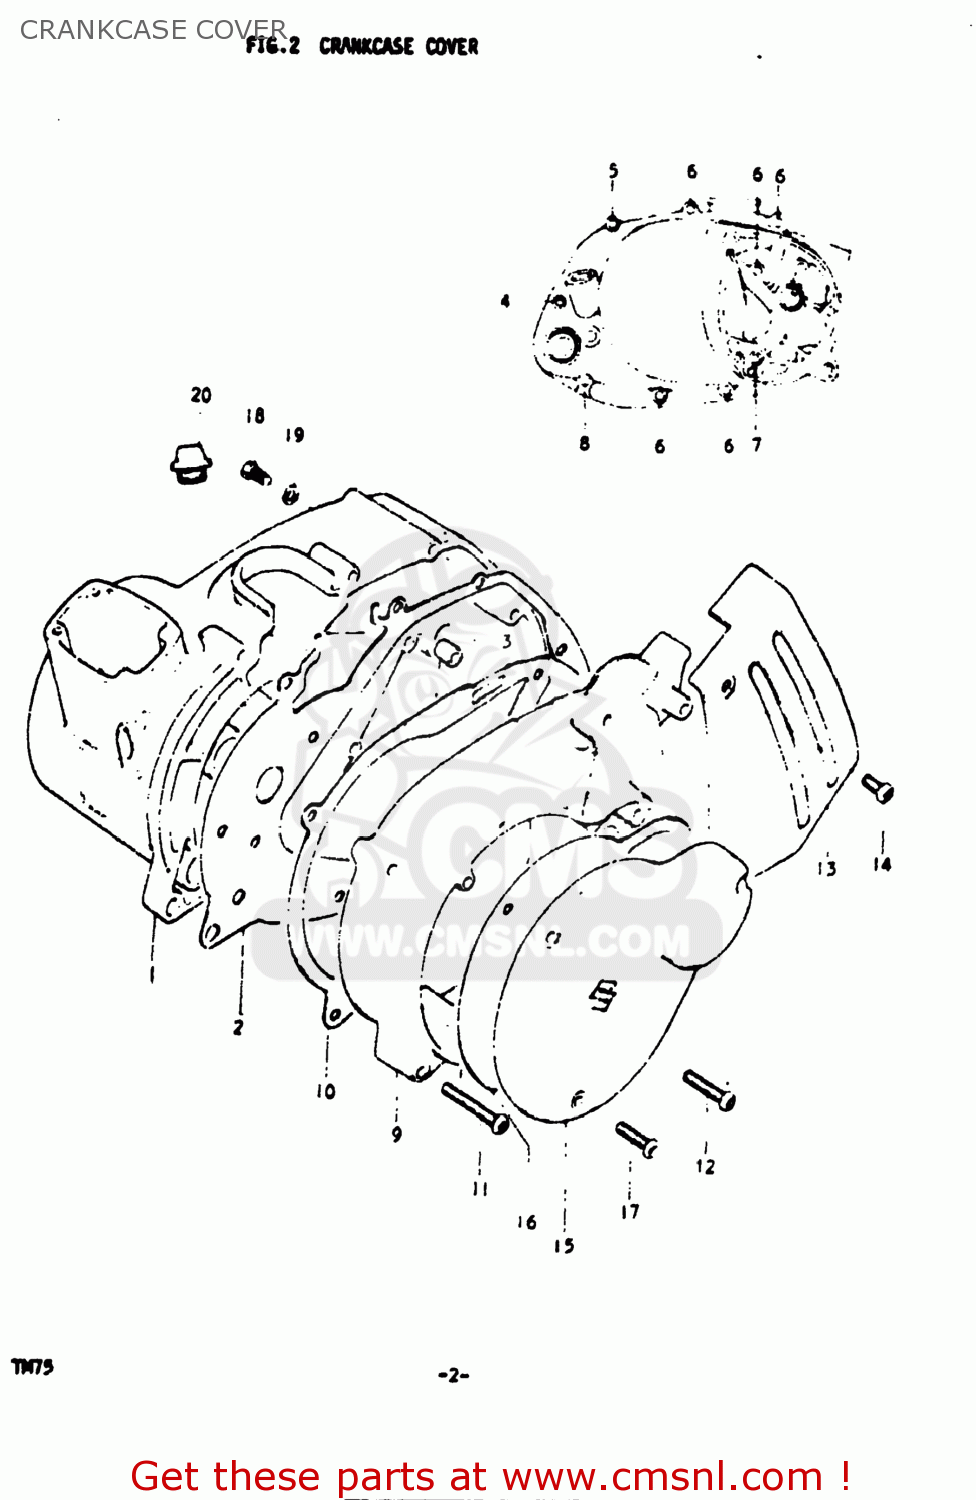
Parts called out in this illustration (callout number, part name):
1	COVER,CLUTCH
2	GASKET,CLUTCH COVER (MCA)
3	PIN
4	SCREW
5	SCREW
6	SCREW (6X35)
7	SCHROEF 5X80
8	SCREW
9	COVER
10	GASKET,MAGNETO COVER (NAS)
11	SCREW (6X35)
12	SCREW
13	COVER,SPROCKET
14	SCREW
15	COVER,SIGNAL GENERATOR
16	GASKET (MCA)
17	SCREW
18	SCREW(6X10)
19	GASKET(6.2X11X1) (NAS)
20	PLUG
